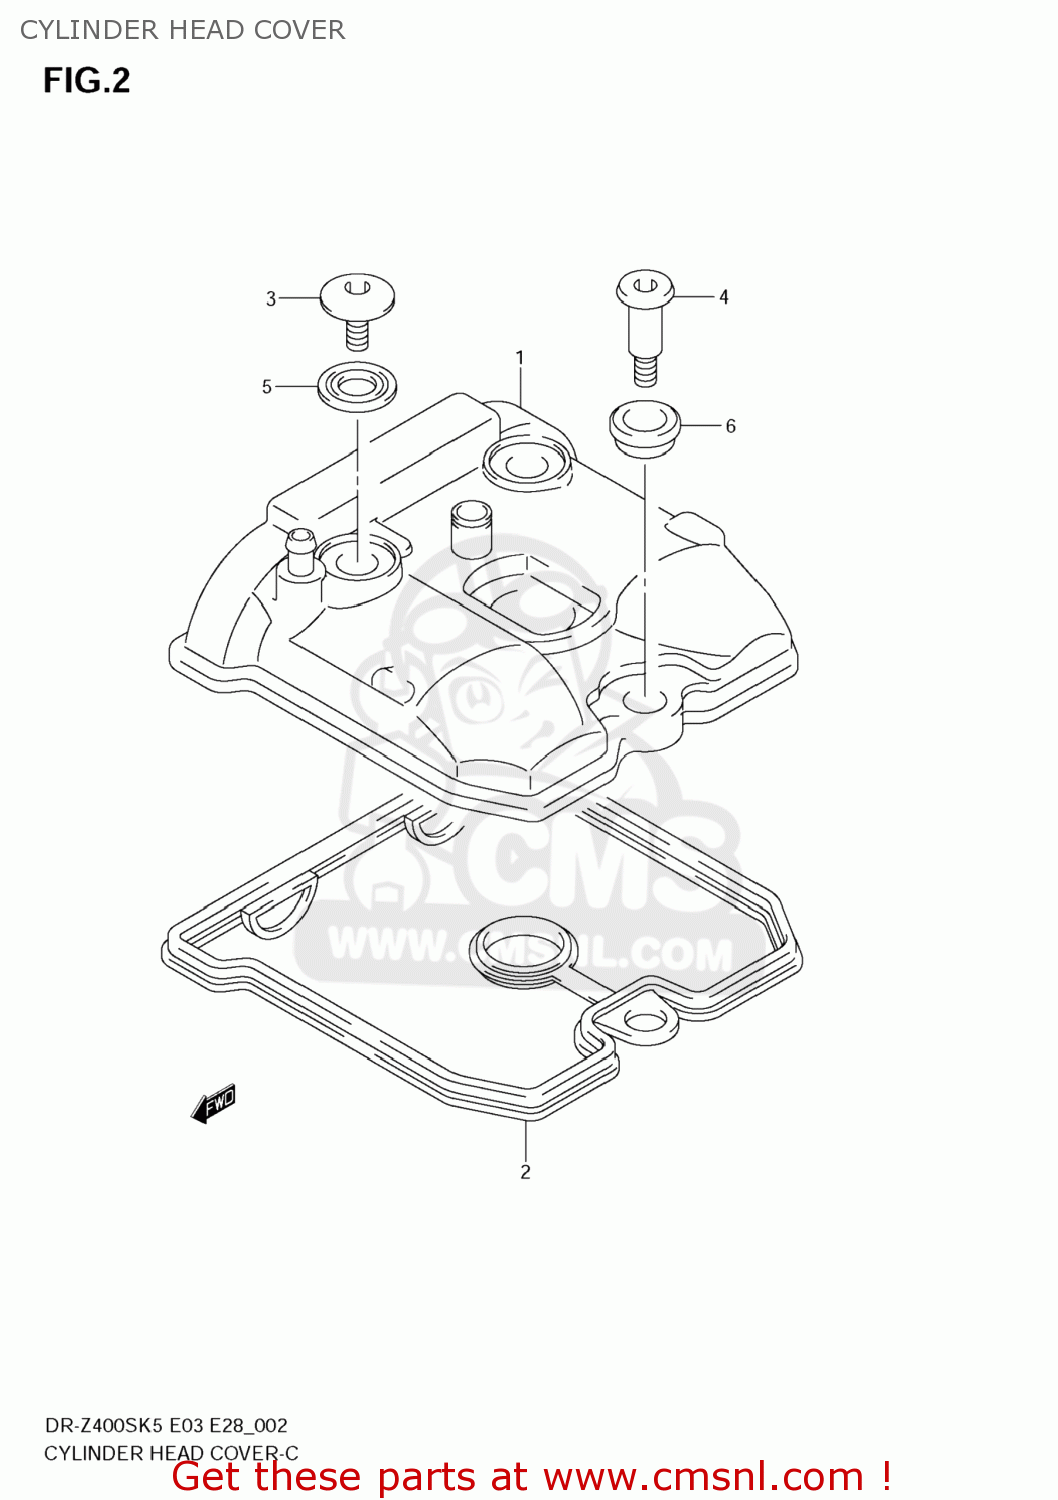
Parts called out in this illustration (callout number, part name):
1	COVER,CYLINDER HEAD
2	GASKET,CYL HEAD COVER (NAS)
3	BOLT(7X17.5)
4	BOLT(7X31)
5	WASHER(10.6X25.5X2.3)
6	CUSHION,HEAD COVER BOLT
